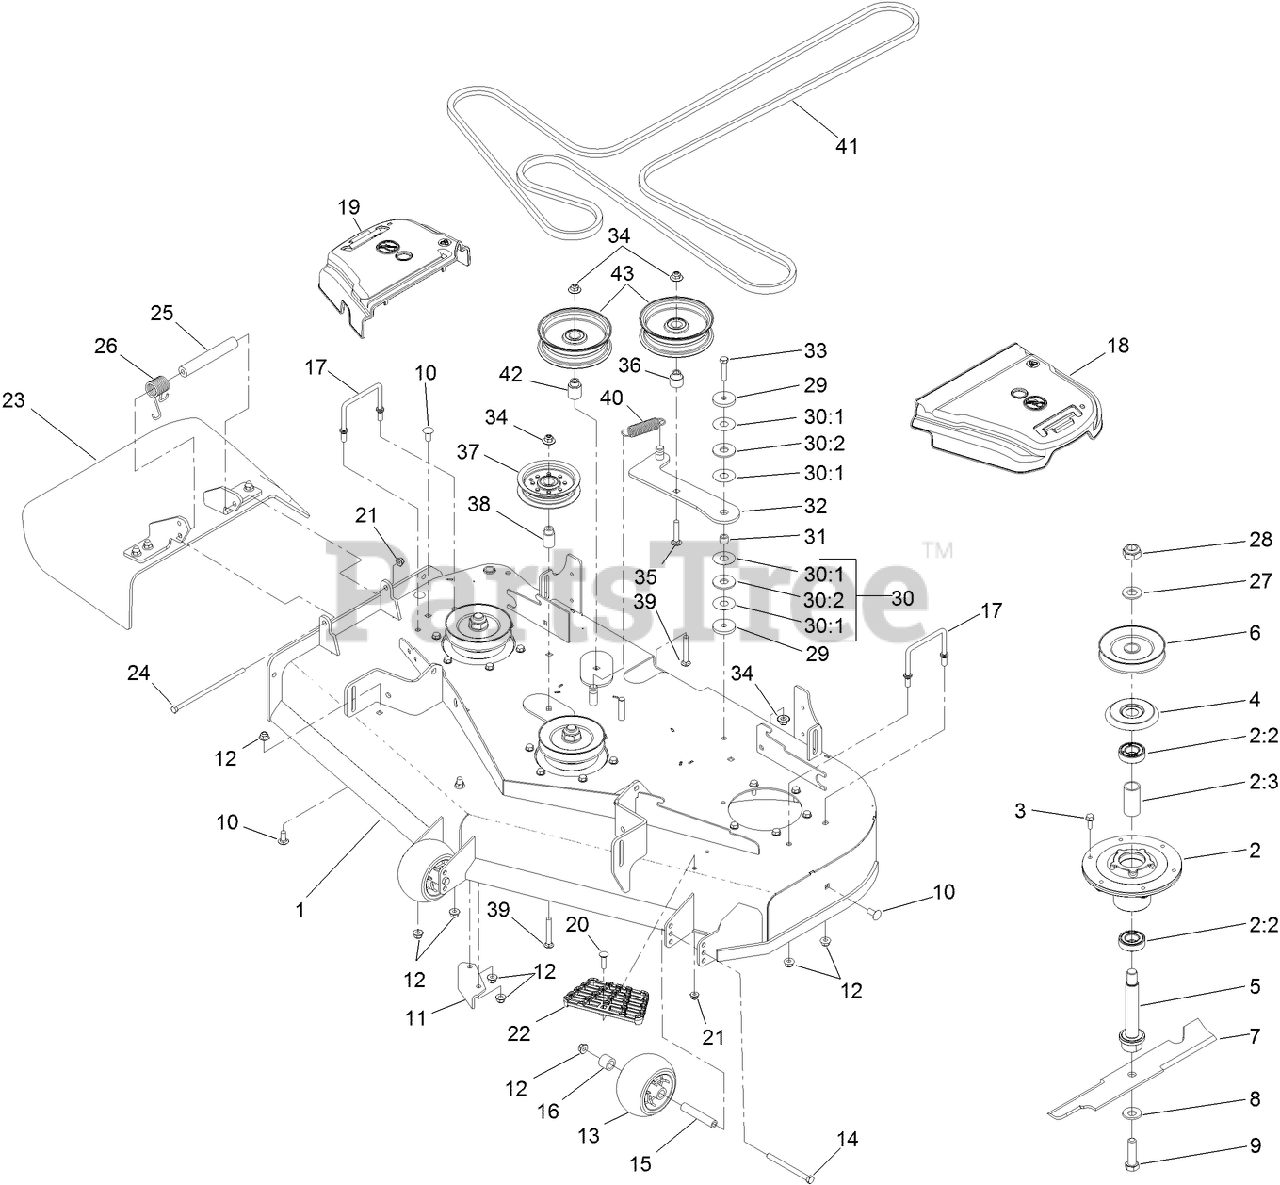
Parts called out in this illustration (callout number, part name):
1	DECK DECAL ASM
2	SPINDLE ASM
2:2	BEARING-BALL
2:3	SPACER-BEARING
3	SCREW-TAPTITE
4	SHIELD-BEARING
5	SHAFT-SPINDLE
6	PULLEY
7	BLADE-ROTARY, 16.5IN (HI FLOW)
8	WASHER-BELLEVILLE
9	SCREW-BLADE
10	SCREW-CARR
11	BAFFLE-DISCHARGE
12	NUT-HF, NI
13	ROLLER-SCALP, ANTI
14	SCREW-HH
15	TUBE-SPANNER
16	TUBE-SPACER
17	WIREFORM-COVER
18	COVER-BELT, LH
19	COVER-BELT, RH
20	SCREW-CARR
21	NUT-HF, NI
22	STEP-DECK
23	DEFLECTOR ASM
24	SCREW-HH
25	SPACER
26	SPRING-TORSION
27	WASHER
28	NUT-LOCK, NI
29	WASHER-PLAIN
30	WASHER-FRICTION, COMPOSITE
30:1	WASHER
30:2	SPACER
31	BUSHING-LEVER, LIFT
32	ARM-IDLER
33	SCREW-HH
34	NUT-FLANGE, NI
35	SCREW-CARR
36	BUSHING-IDLER
37	PULLEY-IDLER
38	BUSHING-IDLER
39	SCREW-CARR
40	SPRING-EXTENSION
41	BELT, DECK DRIVE
42	BUSHING-IDLER
43	IDLER-PULLEY, FLAT
